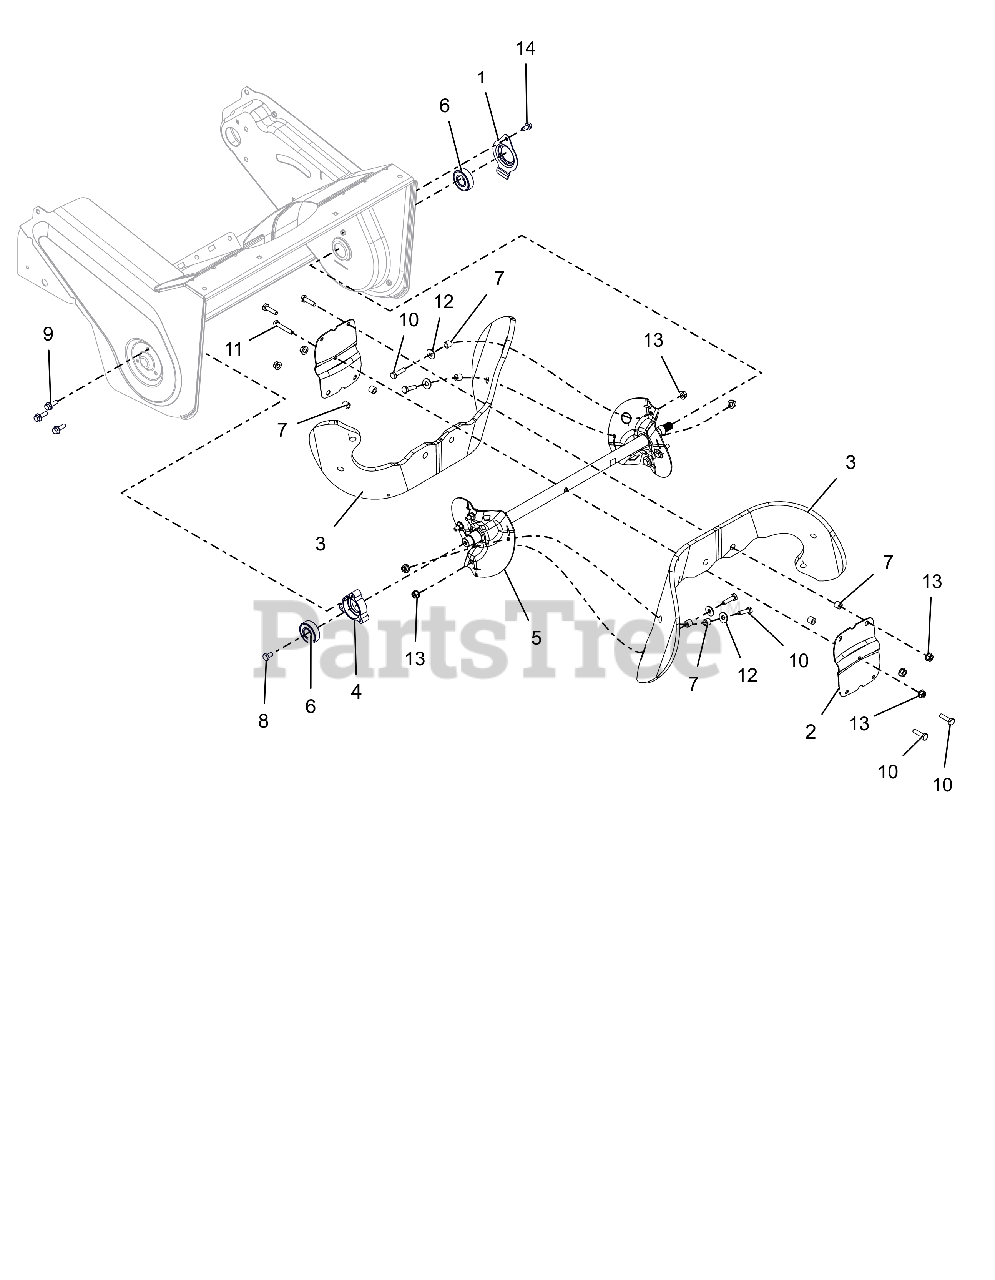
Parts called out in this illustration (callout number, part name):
1	CAP, BRG
2	PLATE, CENTER AUGER
3	FLIGHTING, AUGER
3	KIT, HIGH WEAR PADDLES
4	HOLDER, BEARING - PM
5	AUGER, WELDMENT
6	BRG-BALL .669X1.575X.47(6203Y)
7	BUSHING,.26 ID X .44 OD X .375
8	BLT-HEX .25-20X.50 GR5 EPOXY
9	BLT,HEX-FLG .25-20X.75 G5 BFP
10	@BLT-HEX .25-20X1.00 GR5 YWZC
11	@BLT-HEX .25-20X1.50 GR5 YWZC
12	@WSHR-FL-STL.312X.734X.065 YWZ
13	@NUT-LK-TOP-FLG .25-20 YWZC
14	SCR-TAP .25-20X.50 HWH TR YWZ
